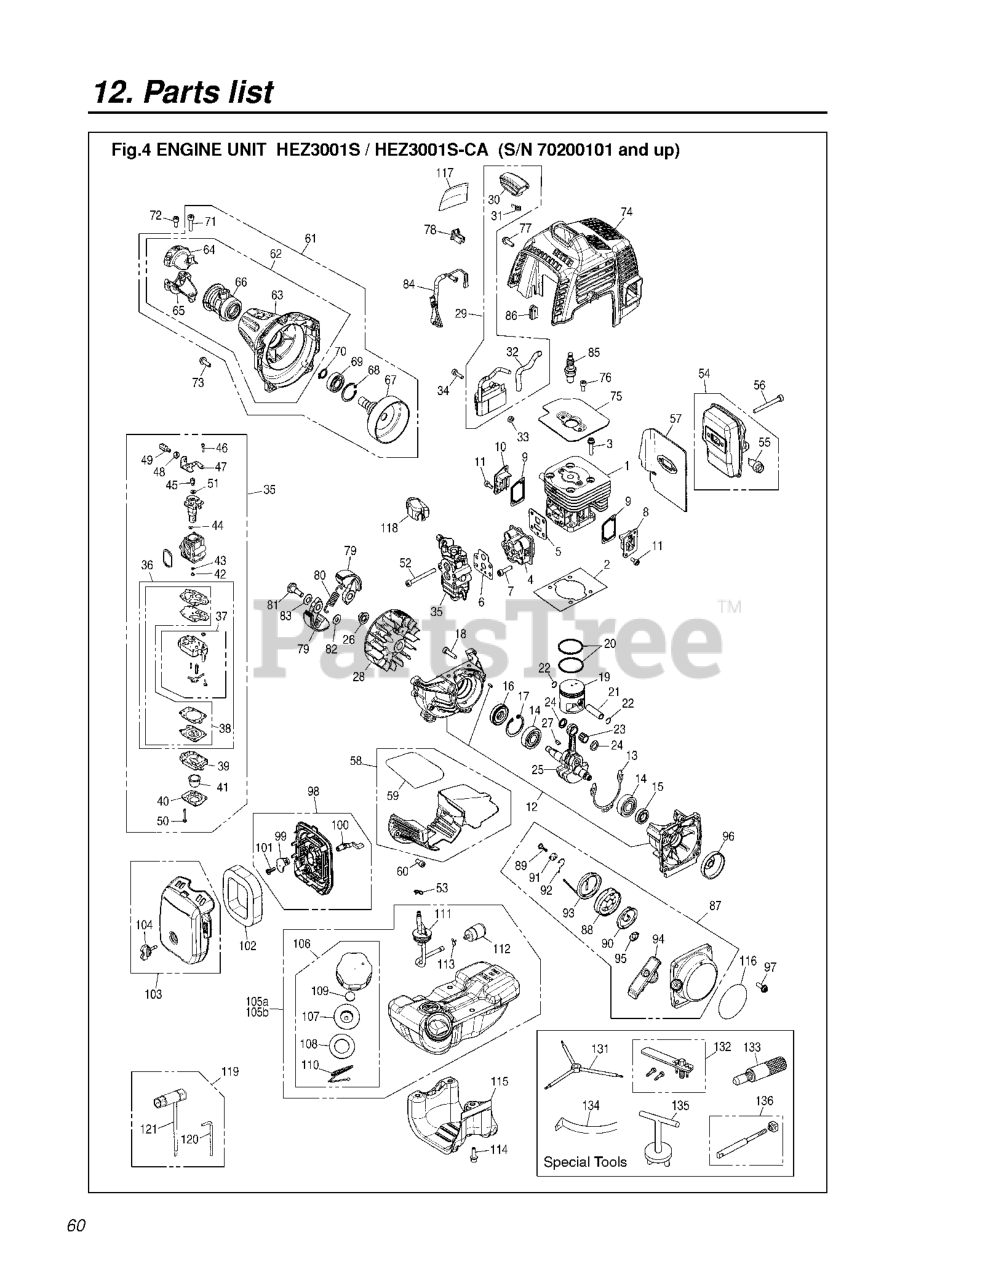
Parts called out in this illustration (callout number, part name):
1	CYLINDER (RPLS 848F6012A1&A2)
2	GASKET BASE
3	BOLT
4	INSULATOR
5	GASKET.INSU
6	GASKET, CARB (RPLS T155113131)
7	BOLT, TORX
8	COVER, TRS
9	GASKET, TR
10	COVER,TRF (RPLS 848F6012D1)
11	BOLT
12	CRANKCASE-C
13	GASKET CASE
14	BEARING
19	PISTON (RPLS 848F6041A1)
20	RING
21	PIN
25	CRANKSHAFT-C
26	NUT
27	KEY
31	SPRING
33	SPACER
35	CARBURETOR (RPLS 848-F60-8101)
36	REBUILD KIT
37	CARBURETOR BODY
38	GASKET KIT
40	1OVER
44	RING
45	SWIVEL
46	SCREW
47	BRACKET
48	NUT
49	ADJUSTER
51	WASHER
53	CLIP
54	MUFFLER ASSY
55	ARRESTER
57	GASKET
61	HOUSING ASSY
62	HOUSING COMP.
64	BRACKET (A) (RPLS T170031211)
65	BRACKET (B)
67	DRUM (RPLS 481031120-22)
69	BEARING
74	COVER.ENGINE
75	RP_PLATE
84	CORD-COMP
85	PLUG CMR7H
87	RECOIL ASSY
90	SPRING, SPIRAL
91	COLLAR
92	SWING ARM
95	PLATE.STOPPER
98	BODY ASSY
99	PLATE.CHOKE
100	LEVER CHOKE
101	SCREW
103	COVER-A (RPLS T155182200)
105A	TANK ASSY (RPLS 848F608501)
107	HOLDER-A
111	PIPE-C
112	FILTER ASSY
113	CLIP
115	GUARD, TANK
119	TOOL SET (RPLS 848-8UD-0120)
121	SOCKET
132	FLYWHEEL PULLER
